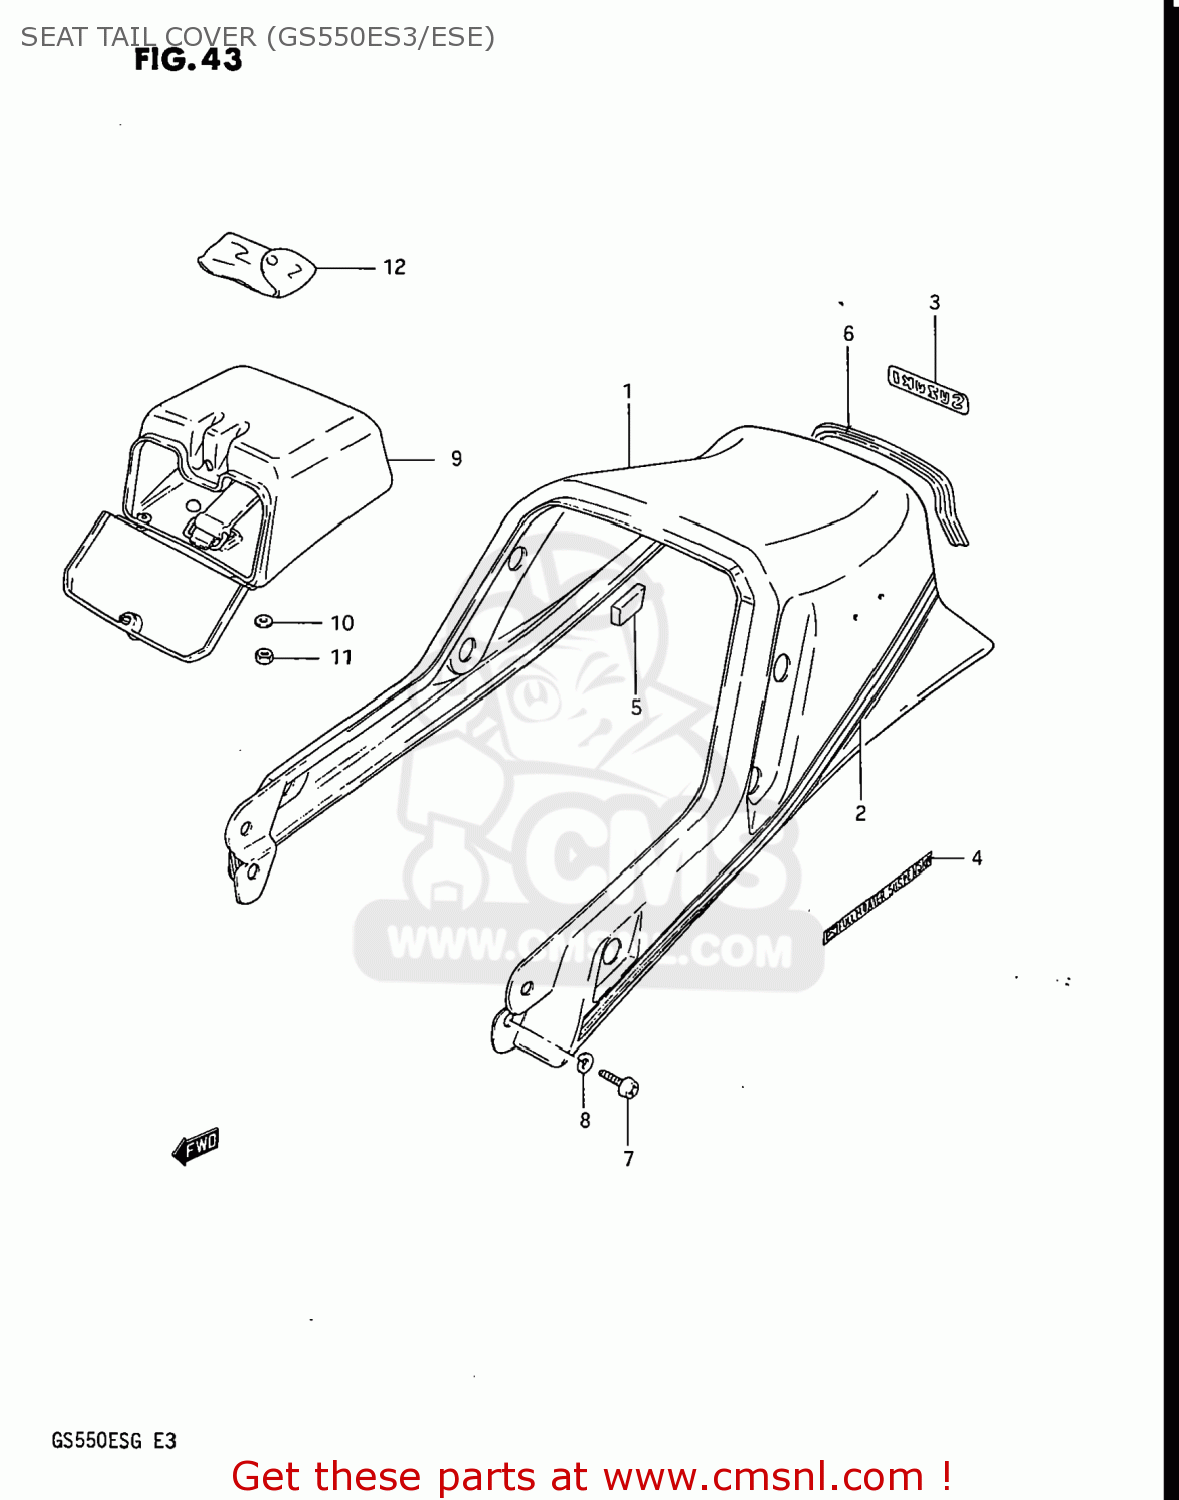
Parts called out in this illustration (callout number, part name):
1	COVER,SEAT TAIL
2	TAPE SET,SEAT TAIL COVER
3	EMBLEM
4	EMBLEM
5	CUSHION
6	BLIND,SEAT TAIL COVER
7	SCREW
8	LOCK WASHER
9	BOX,SEAT TAIL
10	WASHER
11	NUT
12	TOOL ASSY
